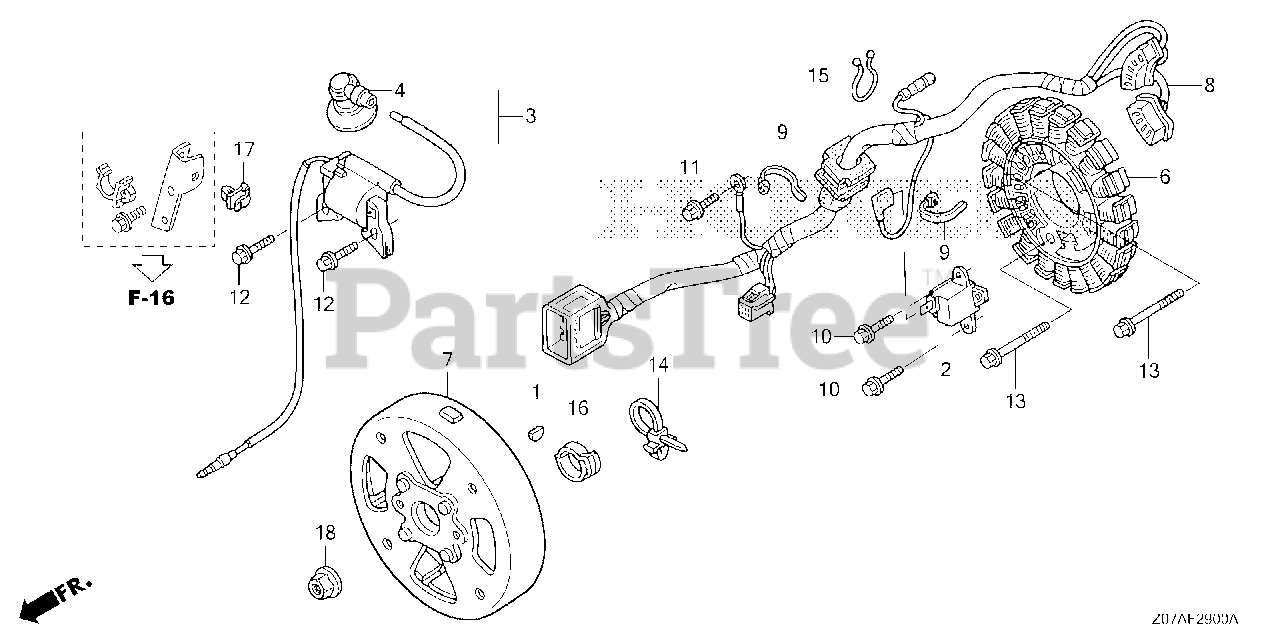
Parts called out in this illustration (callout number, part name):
1	KEY, SPECIAL
2	GENERATOR, PULSE
3	COIL ASSY., IGNITION
4	CAP ASSY., NOISE SUPPRESSOR
5	STATOR ASSY.
8	WIRE HARNESS ASSY., GENERATOR
9	BAND, NYLON
10	BOLT, FLANGE (5X14) (CT200)
11	BOLT, FLANGE (5X10)
12	BOLT, FLANGE (6X20) (CT200)
13	BOLT, FLANGE (5X32) (CT200)
14	BAND, WIRE HARNESS (150MM) (BLUE)
15	BAND, TUBE
16	CLIP, WIRE HARNESS
17	CLIP, WIRE HARNESS
18	NUT, FLANGE (12MM)
